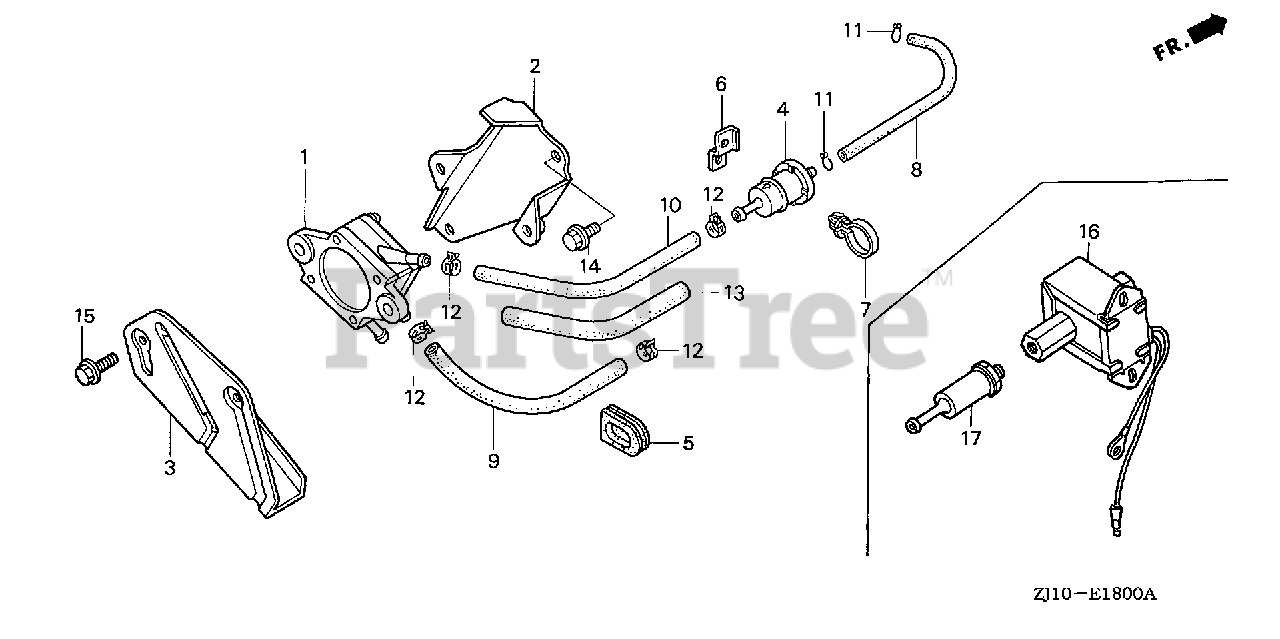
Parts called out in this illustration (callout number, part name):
1	PUMP ASSY., FUEL (MSDS)
2	STAY, FUEL PUMP (NOT AVAILABLE)
4	FILTER, FUEL
5	GROMMET, CORD
6	BASE, CLIP
7	CLIP, WIRE HARNESS
8	BULK HOSE, FUEL (4.5X3000) (4.5X110)
9	BULK HOSE, FUEL (5.5X3000) (5.3X195)
10	BULK HOSE, FUEL (5.5X3000) (5.5X215)
11	CLIP, TUBE (B8)
12	CLAMP, TUBE (D10.5)
13	BULK HOSE, VINYL (11X13X3000) (11X13X160)
14	BOLT, FLANGE (6X8)
15	BOLT, FLANGE (6X14)
